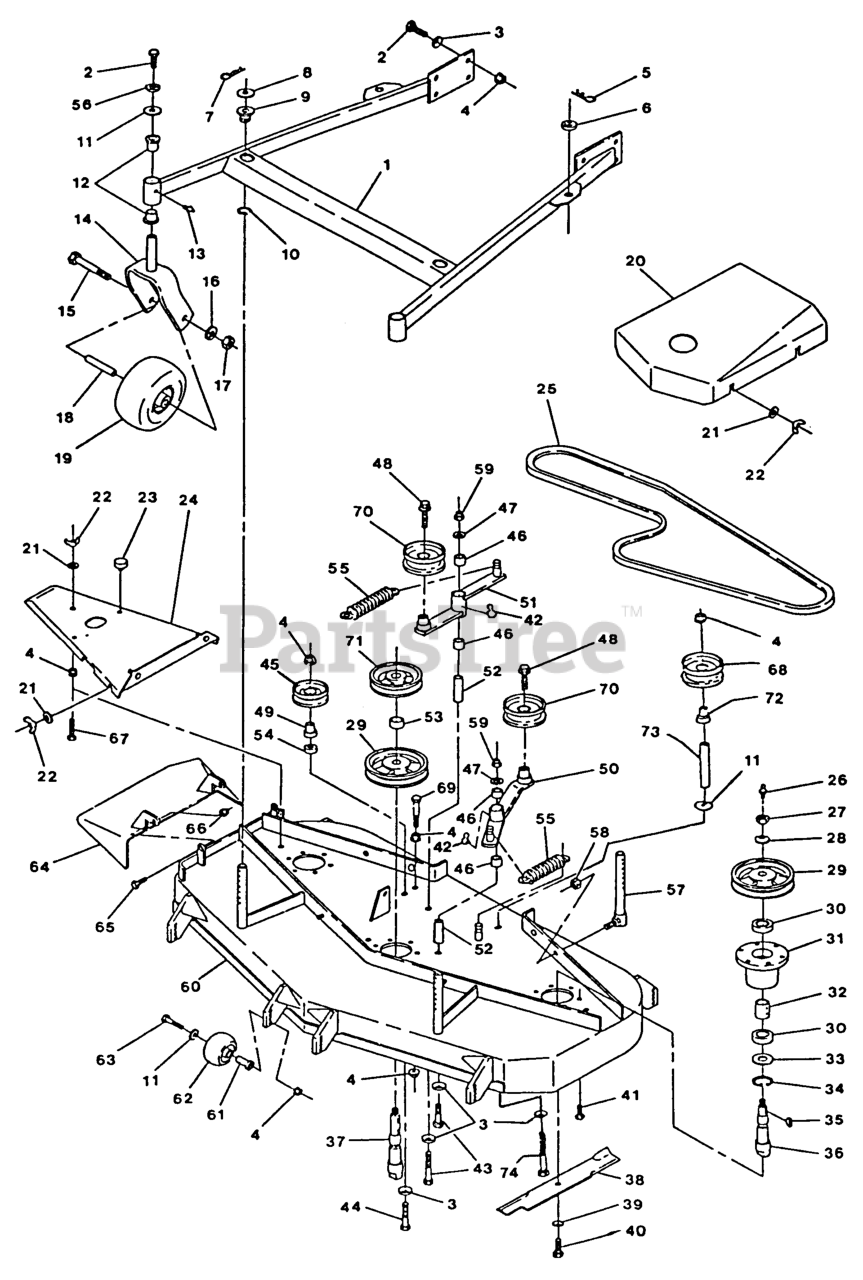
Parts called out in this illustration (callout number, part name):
5	PIN,HAIR COTTER
8	WASHER-FLAT
9	BUSHING-DECK
22	NUT-WING
24	WLD,DECK COVER
25	BELT-DRIVE, BLADE
28	WASHER-SPRING
29	SHEAVE,BLADE DRIVE
32	SPACER,BEARING
33	SEAL,MECHANICAL DUST
34	RING,SNAP WLDS N5000-244
36	SPINDLE-OUTER BLADE
37	SPINDLE-CENTER BLADE
39	WASHER-SPRING
41	SCRW,TPTTE HH
43	SCREW-HH
46	SLEEVE-BEARING
49	BUSHING-IDLER
50	Arm Weld - Dk. Dr. Idler
51	Arm Weld - Dk. Idler Arm
52	BUSHING-PIVOT, IDLER
53	SPACER-TUBE
55	SPRING-EXTENSION
61	BUSHING-ROLLER
62	ROLLER-SCALP, ANTI
63	SCRWCAPHH
68	PULLEY-IDLER
70	IDLER,PULLEY
72	BUSHING,IDLER
73	SPACER-FENDER
